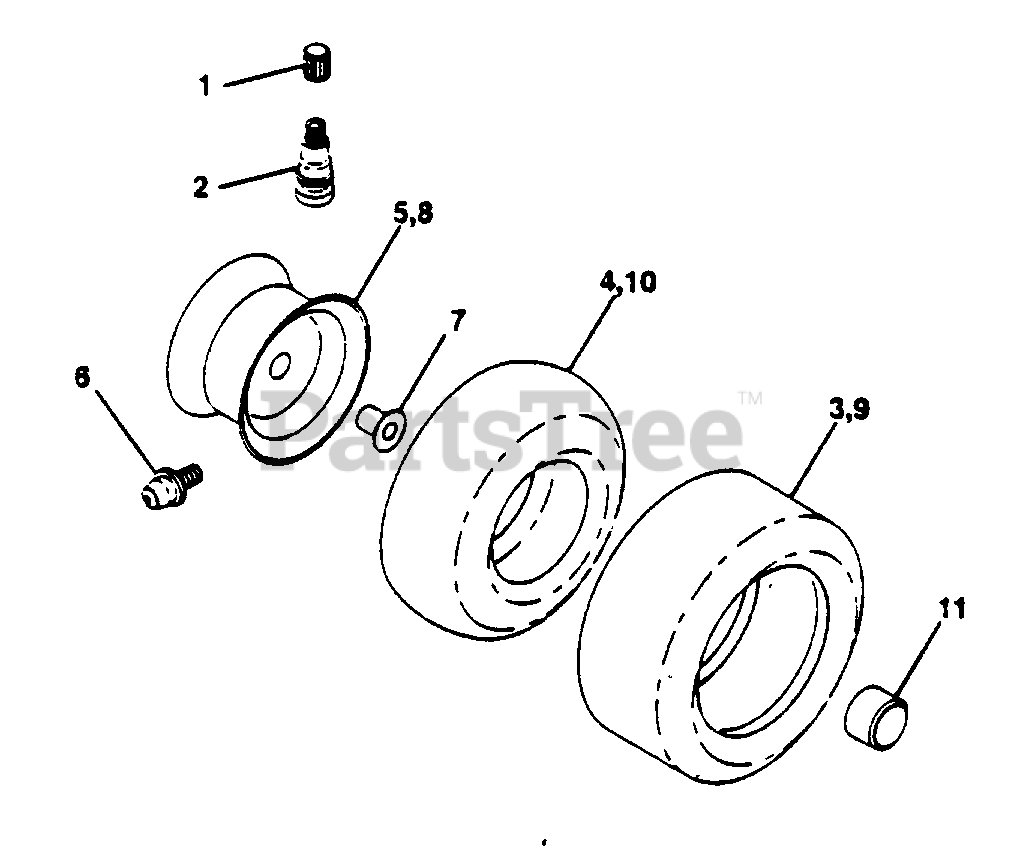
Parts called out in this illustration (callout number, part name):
1	Cap Valve Tire (AYP part number)
2	Stem Valve (AYP part number)
3	Tire F Ts 15 X 6 0 - 6 Service (AYP part number)
4	Tube Front (Service Item Only)
5	Rim Asm 8"rear White Service (AYP part number)
6	Fitting Grease (Front Wheel Only) (AYP part number)
7	Bearing Flange (Front Wheel Only) (AYP part number)
8	Rim Asm 6" front White Service (AYP part number)
9	Tire R Ts 20 X 10 - 8 Service (AYP part number)
10	Tube Rear (Service Item Only) (AYP part number)
11	Cap Hub Axle Black 1.50 x 1.00 (AYP part number)
